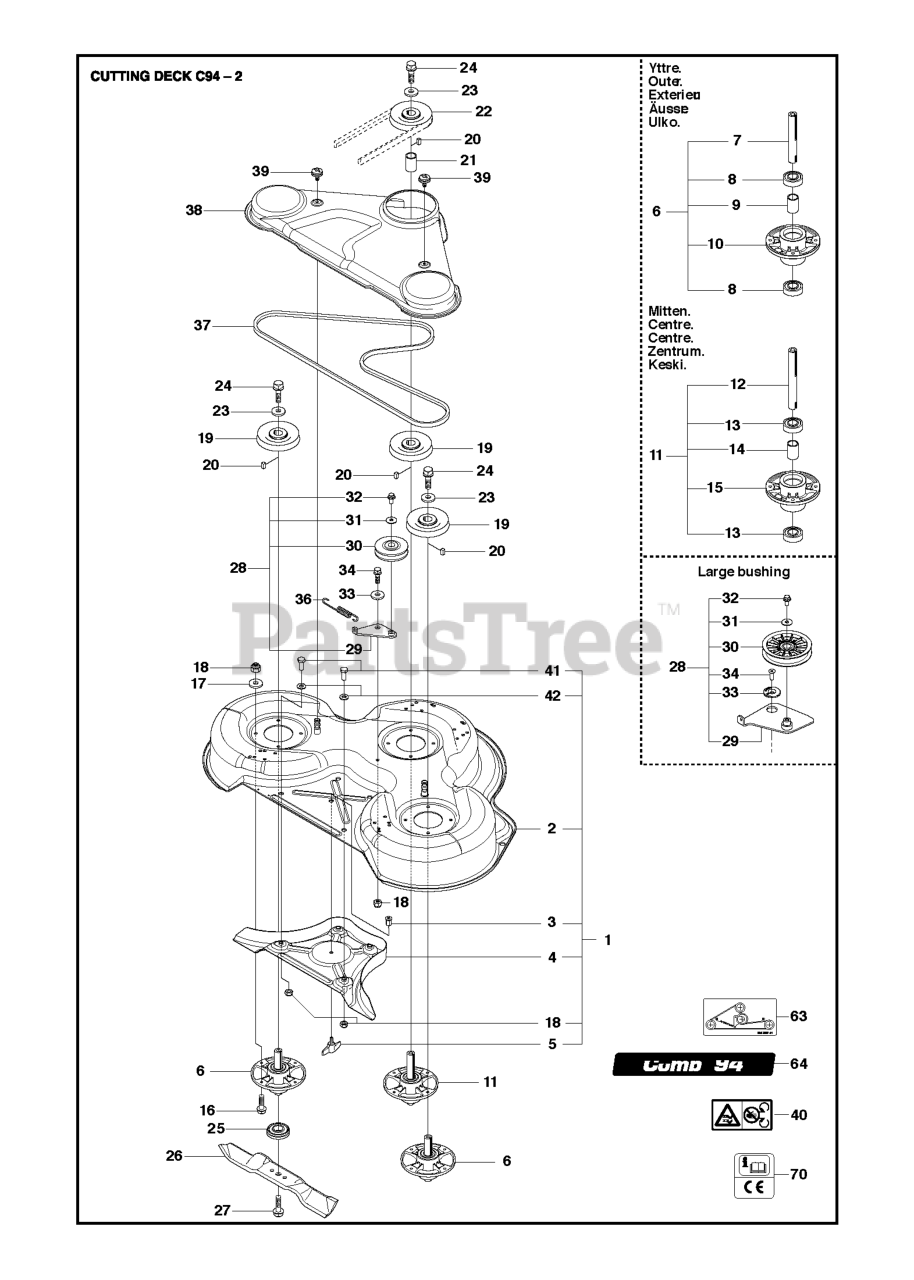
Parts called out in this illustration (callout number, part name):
4	PLUG C93 & C94
6	BLADE HOUSING ASSY
9	SPACING SLEEVE
10	BEARING HOUSING
14	SPACING SLEEVE
15	BEARING HOUSING
17	WASHER BRB 8.4X17
18	LOCKNUT M8
21	SPACING SLEEVE
25	BLADE BRACKET
28	Belt Tensioners
29	BRACKET
33	WASHER SHOULDER ASSY
33	WASHER
34	SCREW
42	WASHER BRB 8.4X17
